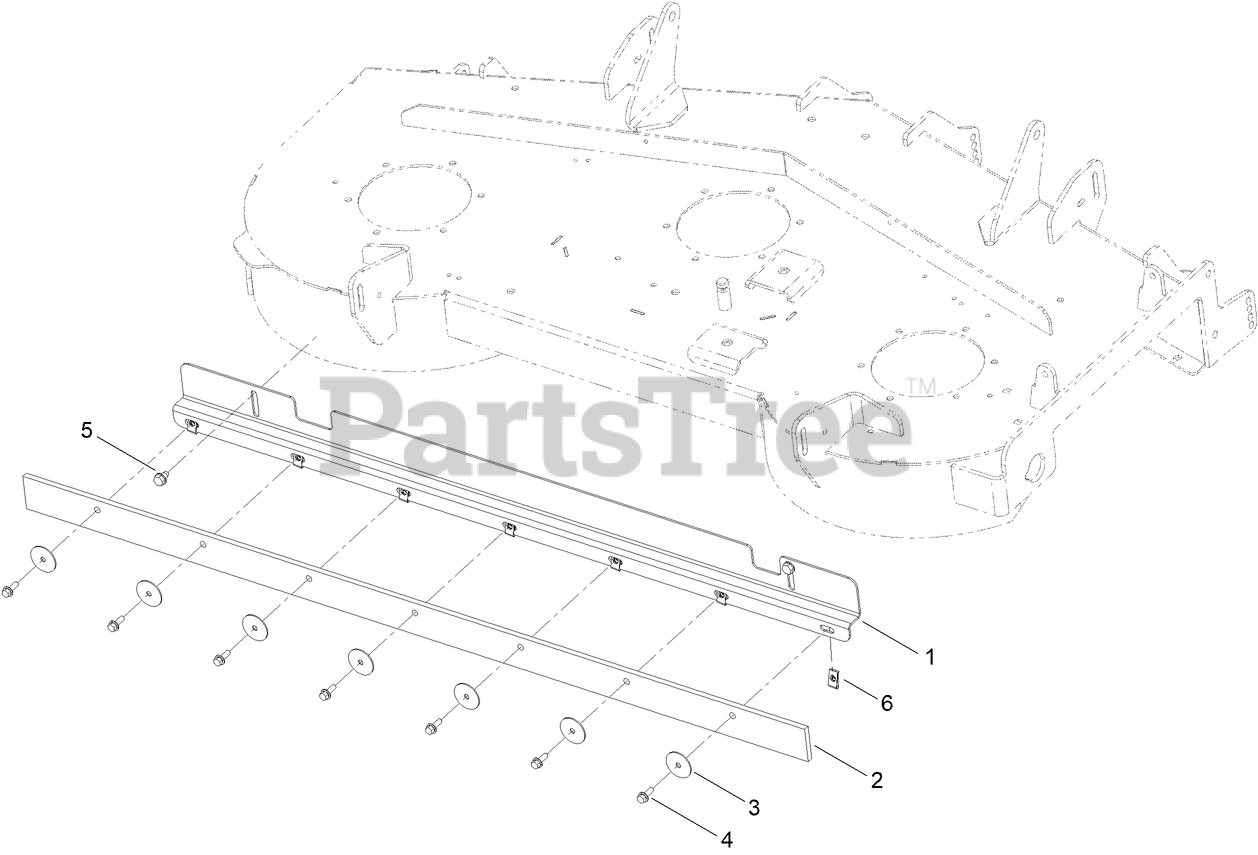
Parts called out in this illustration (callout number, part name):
1	BRACKET-STRIPING, 48"
3	WASHER-FENDER
4	SCREW-HHF
5	SCREW-HWH, THD ROLL
6	NUT-SPEED
